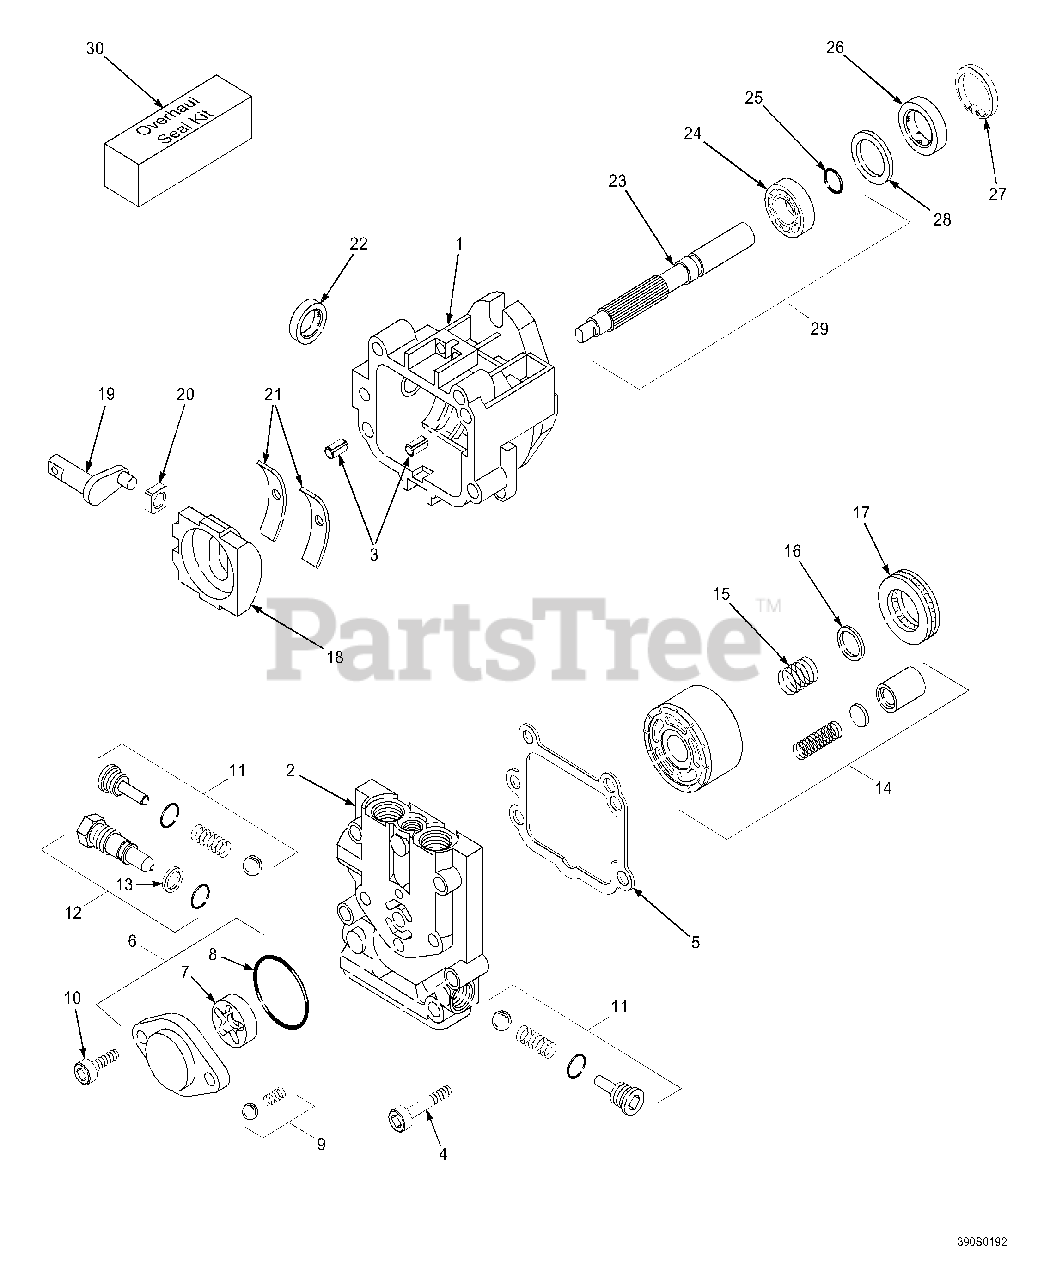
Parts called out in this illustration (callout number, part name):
1	Housing Kit
2	End Cap
3	Straight Headless Pin
4	Socket Head Screw
5	End Cap Gasket
6	Charge Pump Kit
7	Gerotor Assembly
9	Charge Relief Valve Kit
10	Socket Head Screw
11	Check Valve Kit
12	Bypass Valve Kit
13	Backup Ring
14	Cylinder Block Kit
15	Block Spring
16	Block Thrust Washer
17	Roller Thrust Bearing
18	Swash Plate
19	Trunnion Arm
20	Guide Slot
21	Cradle Bearing
23	Pump Shaft
24	Ball Bearing
25	Retaining Ring
27	Retaining Ring
29	Shaft Kit
30	Overhaul Seal Kit
